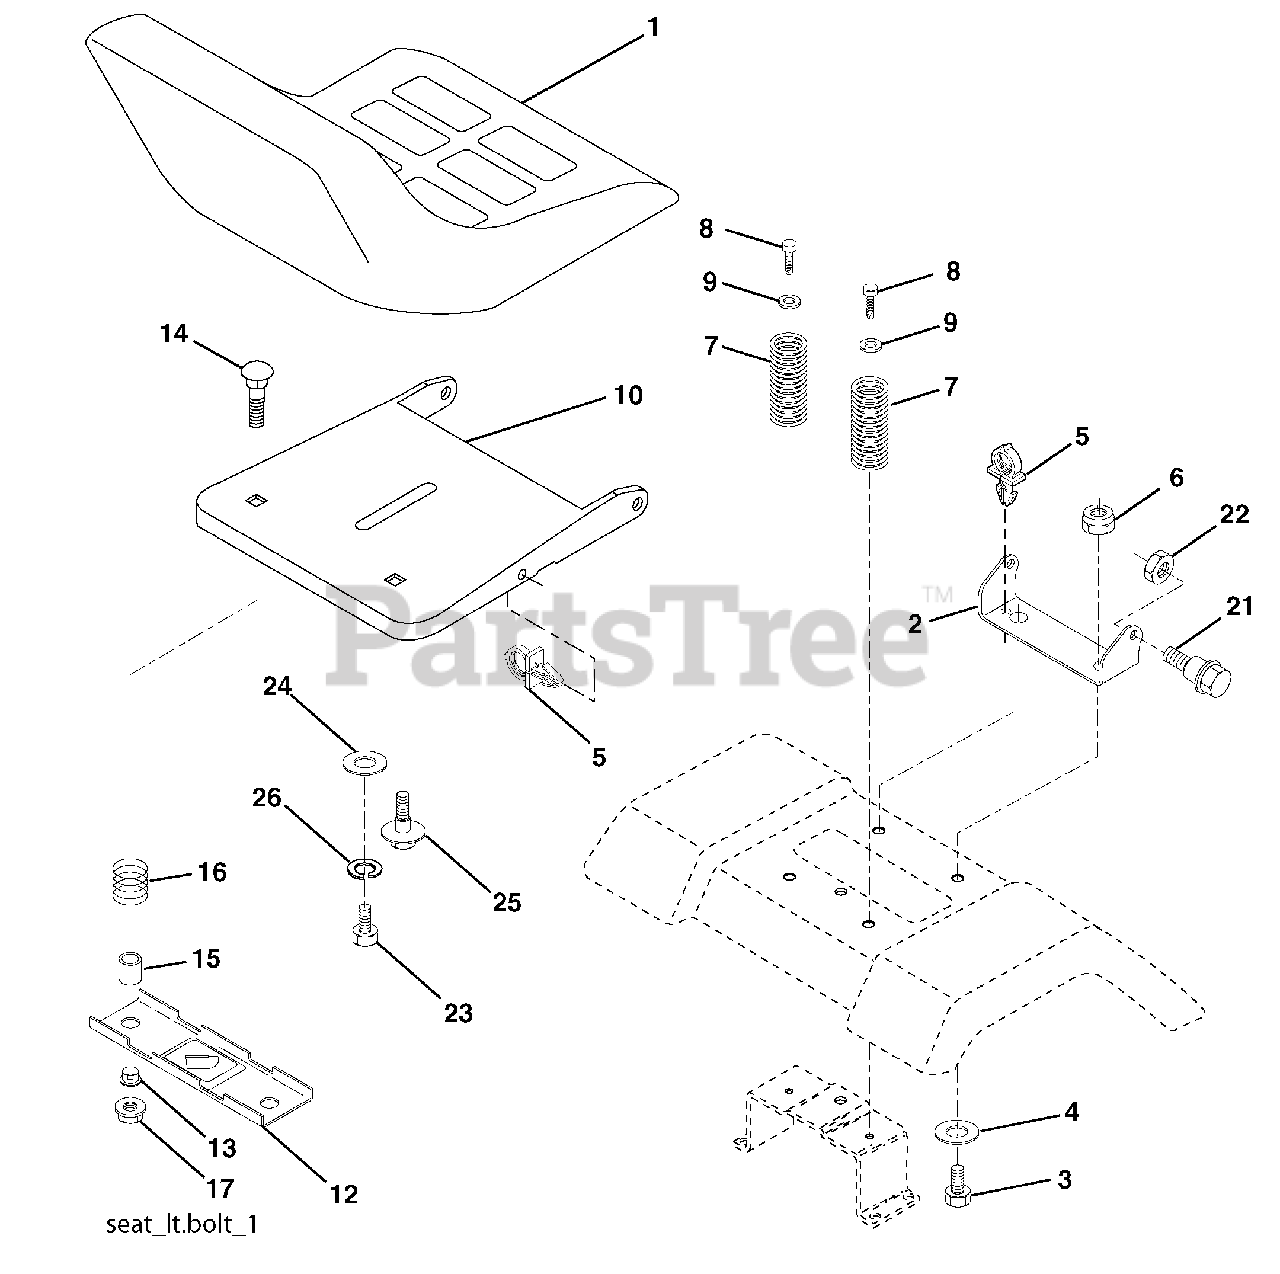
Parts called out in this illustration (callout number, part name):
1	Seat
2	Bracket Seat Pivot
3	Bolt Hex 3/8 - 16 x 1
4	Washer 13/32 x 1 x10 Ga.
5	Clip Push-In Hinged
6	Nut Lock Hex w/Ins 3/8 - 16
7	Spring Seat Cprsn 2 250 Blk Zi
8	Screw 3/8-16 x 1.5
9	Washer 13/32 x 1 x 14 Ga.
10	Pan Pnt Seat (Blk)
12	Bracket Pnt Mounting Switch
13	Bushing Snap Blk Nyl
14	Bolt Rdhd Sht Nk 1/4 - 20 x 1 -1/2
15	Spacer Split .28 x .96
16	Spring Cprsn
17	Nut Lock 1/4 Lge Flg
21	Bolt Shoul der 5/16-18 unc-2A
22	Nut Lock Hex w/Ins 5/16 - 18
23	Bolt Hex
24	Washer 17/32 x 1-3/16 x 12 Ga.
25	Bolt Shoul der 5/16-18 x .62
26	Washer Lock Hvy Hlcl Spr 1/2
